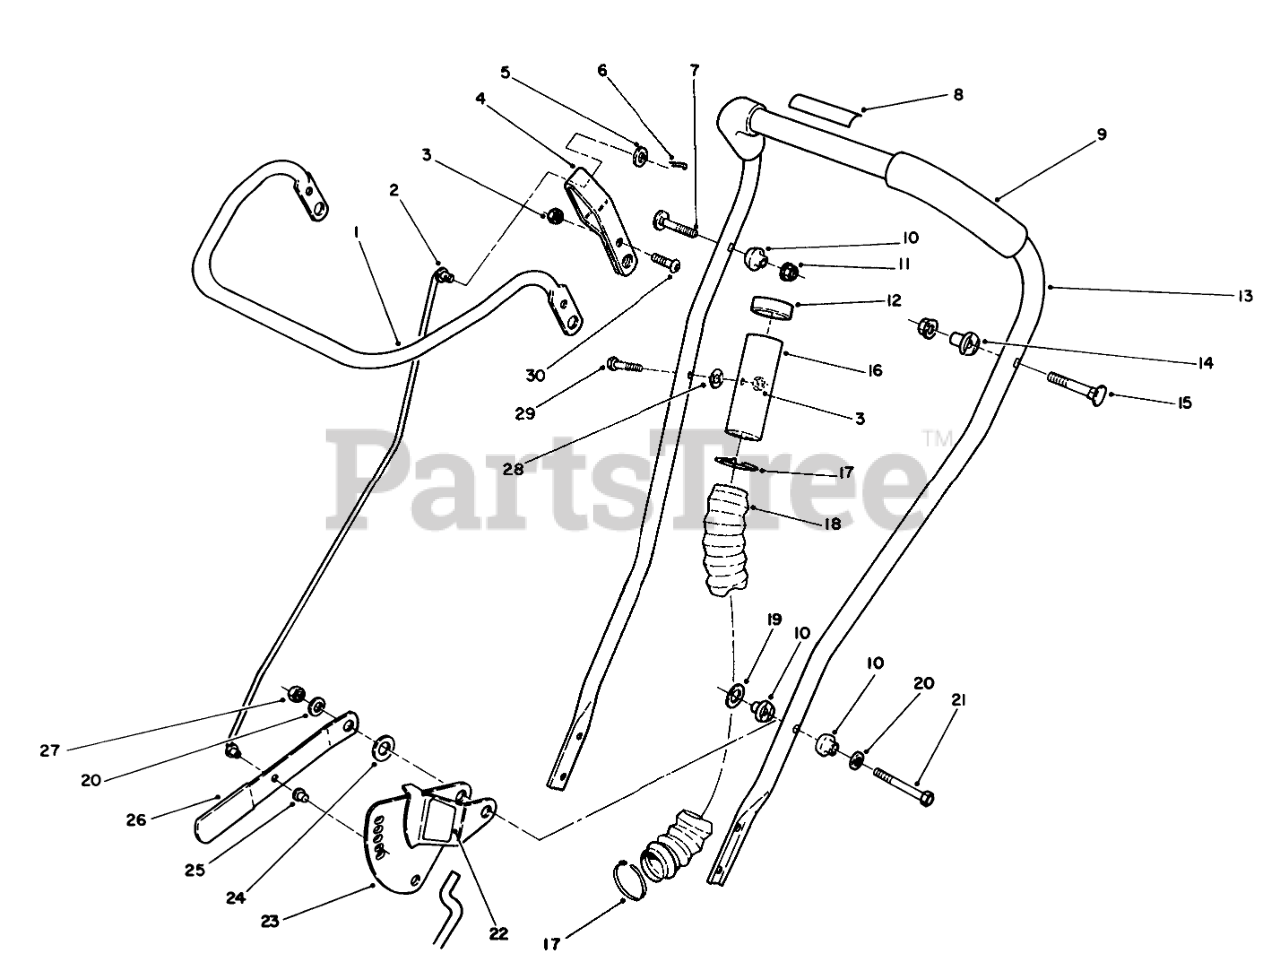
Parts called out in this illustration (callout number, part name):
1	Bar-Control
2	UPPER CONTROL ROD
3	NUT-LOCK, NI
4	CONTROL BAR BRKT.
5	WASHER-FLAT
6	PIN-COTTER
7	SCREW-HANDLE
8	DECAL
9	FOAM GRIP
10	PIVOT SPACER
11	NUT-LOCK, NI
12	BLACK CAPLUG
13	UPPER HANDLE
14	SPACER-SUPPORT
15	5/16-18 X 2 HNDLE SCREW
16	AIR CLNR HOSE TIP
17	TIE-CABLE
18	AIR CLEANER HOSE
19	WASHER
20	WASHER-PLAIN
21	SCREW-HH
22	DECAL
23	ADJ.PLATE WA
24	WASHER
25	PUSHNUT
26	ADJ.HANDLE
27	NUT-LOCK, NI
28	WASHER
29	SCREW-HH
30	SCREW-HSBH
